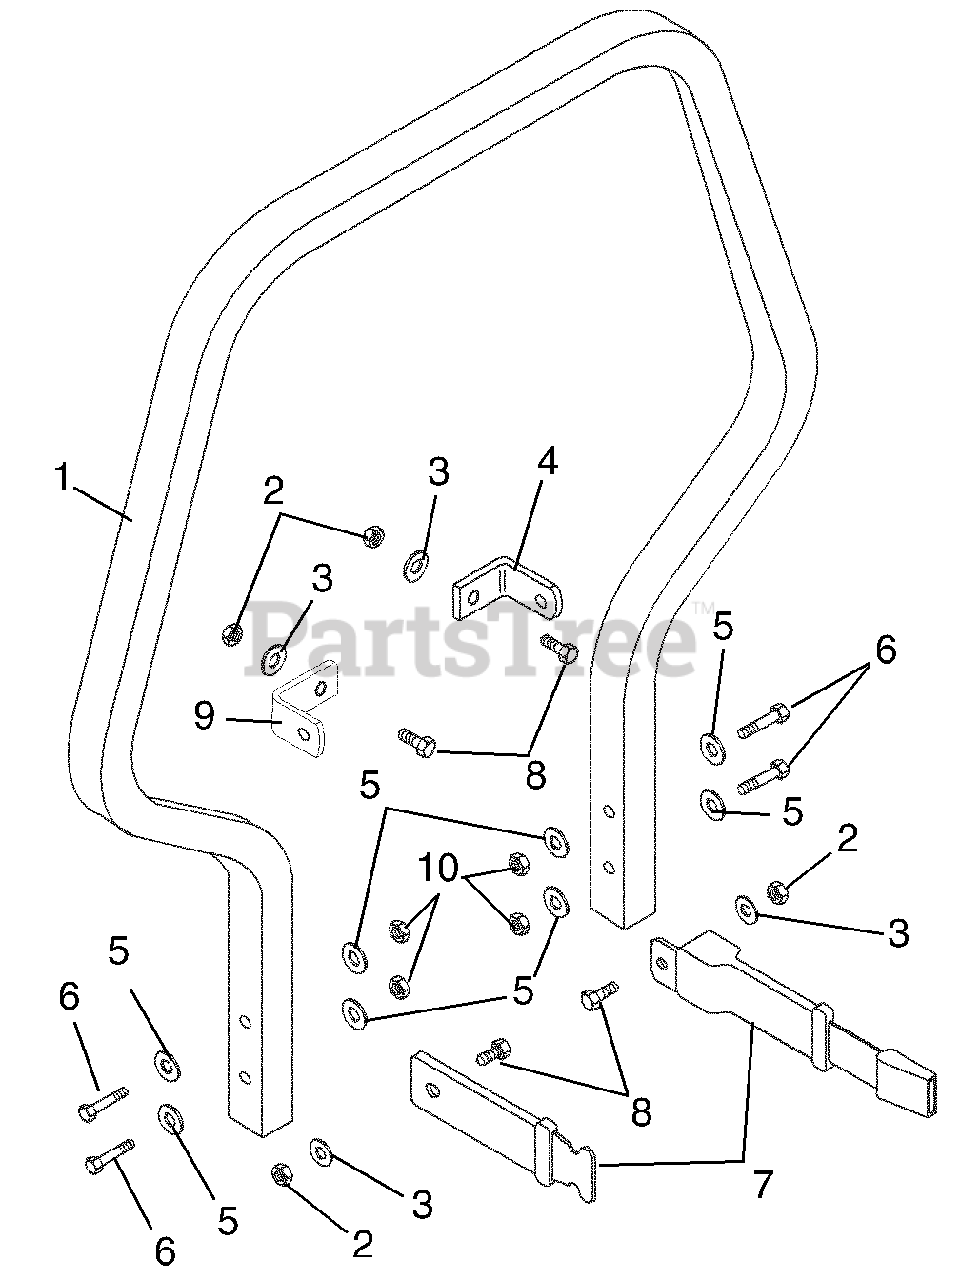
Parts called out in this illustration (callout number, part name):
1	ROLLBAR ASSY, INT Z
2	@NUT-LK-CTR .44-14 YWZC
3	@WSHR-FL-STL.50X1.25X.083 YWZC
4	BRACKET, SEAT BELT MOUNT, LH
5	@WSHR-FL-STL.563X1.38X.109YWZC
6	@BLT-HEX .50-13X3.00 GR5 YWZC
7	ASSY, SEAT BELT
8	@BLT-HEX .44-14X1.00 GR5 YWZC
9	BRACKET, SEAT BELT MOUNT, RH
10	@NUT-LK-NYL .50-13 YWZC
